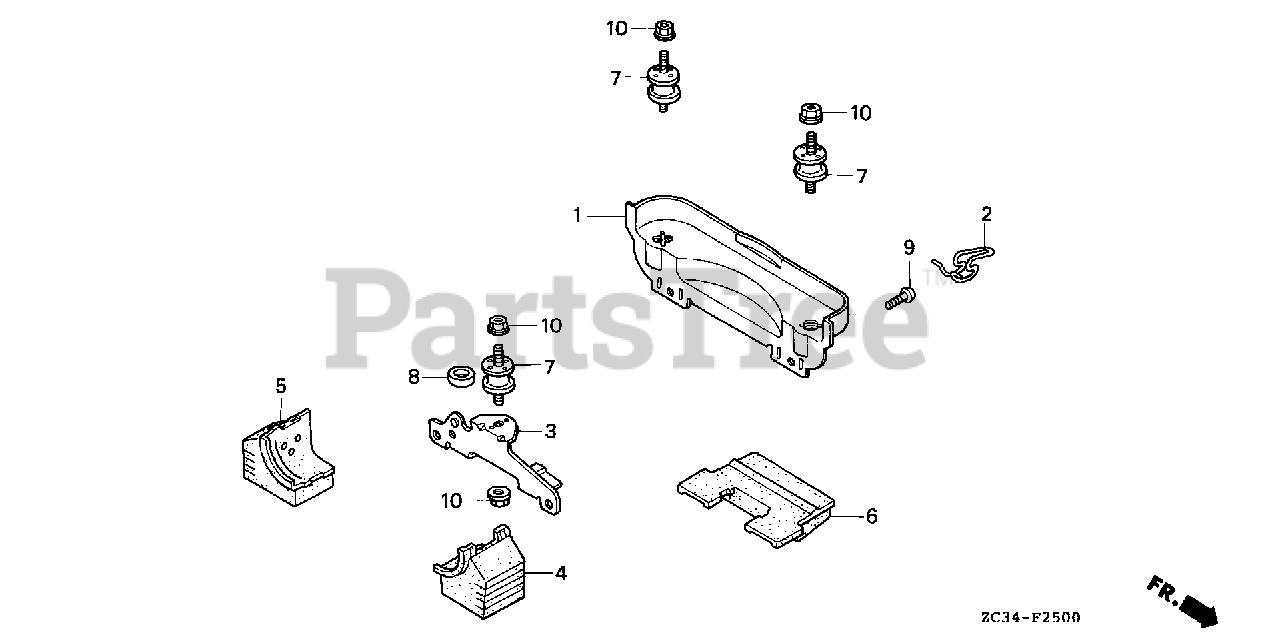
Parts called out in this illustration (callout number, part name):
1	BRACKET, RR. ENGINE MOUNTING
2	SPRING, SETTING
3	BRACKET, FR. ENGINE MOUNTING
4	RUBBER, R. (LOWER)
5	RUBBER, L. (LOWER)
6	RUBBER, RR. (LOWER)
7	RUBBER, ENGINE MOUNTING
8	RUBBER, BUMP STOP
9	SCREW, PAN (5X16)
10	NUT, FLANGE (6MM)
